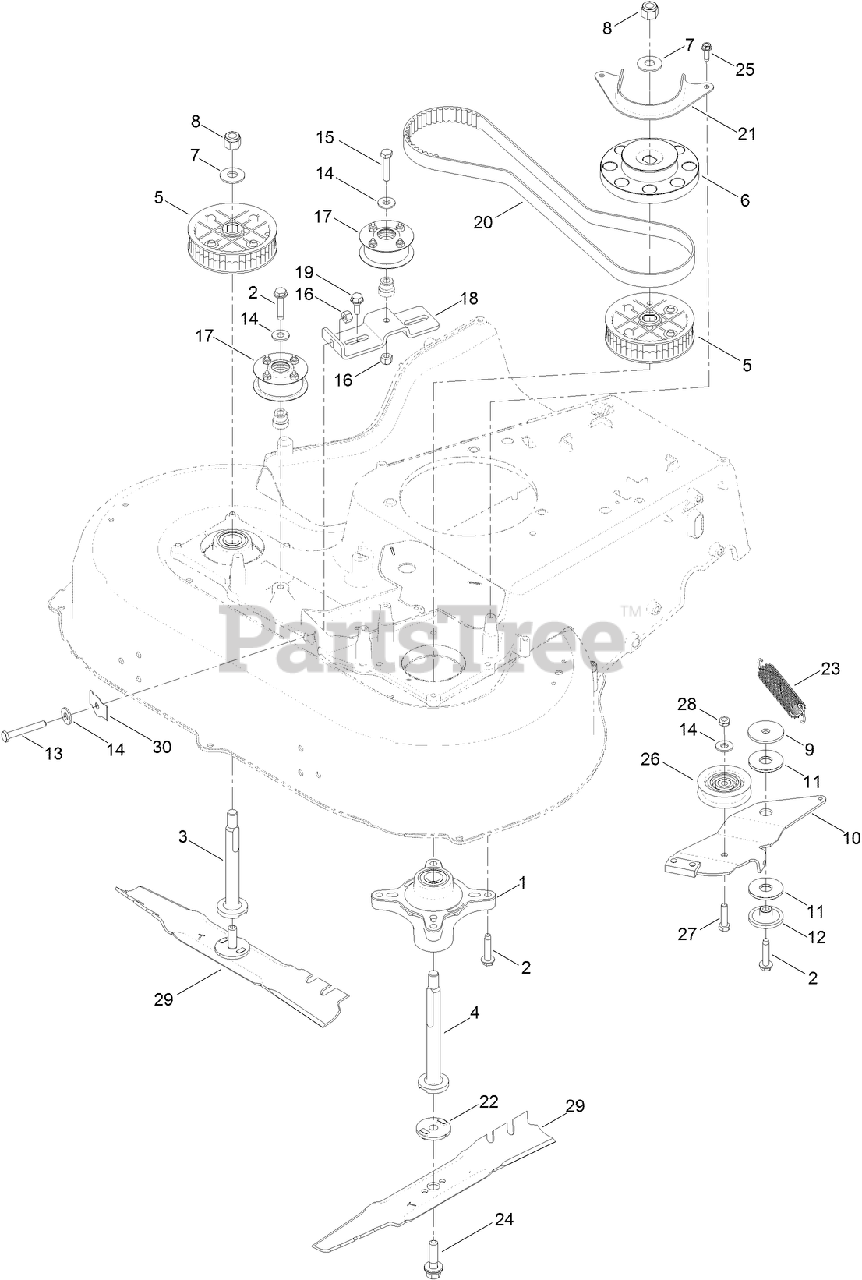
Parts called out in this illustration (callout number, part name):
3	SHAFT-SPINDLE
4	SHAFT-SPINDLE
5	SPROCKET
6	PULLEY-BRAKE, SPINDLE
7	WASHER-SPRING
8	NUT-HEX
9	WASHER-REBOUND
10	ARM-BRAKE
11	WASHER-FRICTION, COMPOSITE
13	BOLT-TAP, HH
14	WASHER-FLAT
15	SCREW-HH
16	NUT-LOCK, NI
17	PULLEY KIT
18	BRACKET-IDLER
19	SCREW-SHOULDER,HWH
20	BELT-SYNCHRONOUS
21	GUIDE-BELT, SPINDLE
22	ADAPTER-BLADE
23	SPRING-EXTENSION, BRAKE
24	BOLT-BLADE
25	SCREW-HWHTF
26	PULLEY-IDLER
27	SCREW-HH
28	NUT-LOCK, NI
29	BLADE-ROTARY
30	SPRING-FLAT
